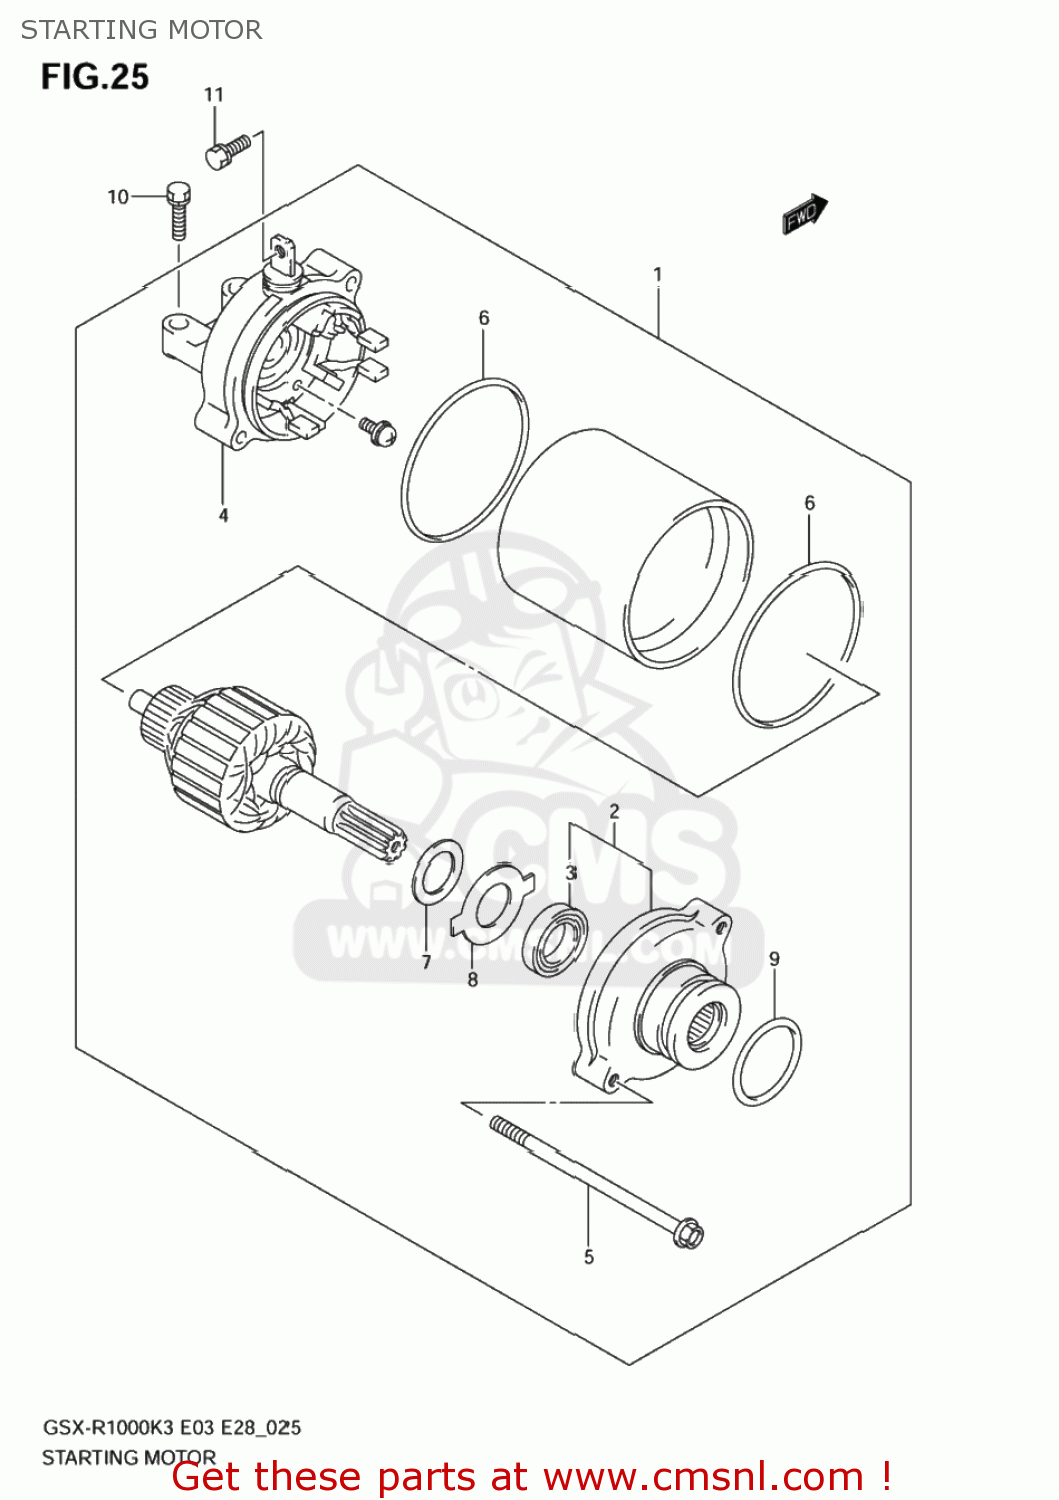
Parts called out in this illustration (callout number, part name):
1	MOTOR ASSY,STARTING
2	HOUSING ASSY
3	SEAL,OIL
4	FRAME ASSY
5	BOLT
6	O RING
7	SHIM
8	PLATE,LOCK
9	O RING(D:3,ID:24.5)
10	BOLT(6X20)
11	SCREW(5X8)
